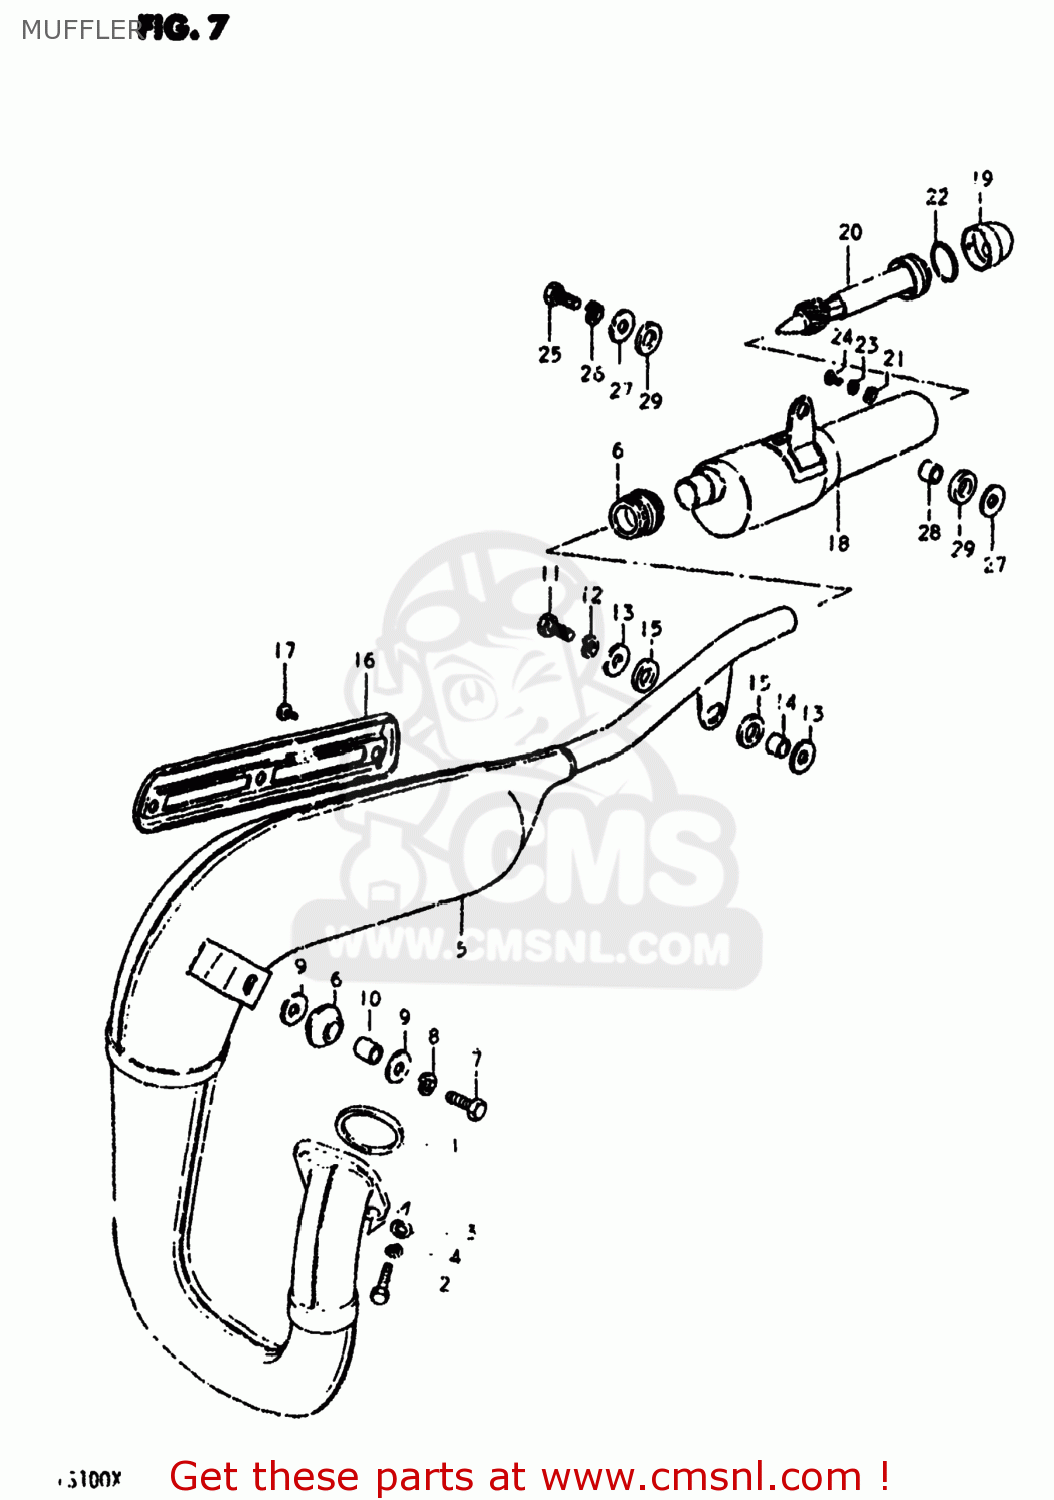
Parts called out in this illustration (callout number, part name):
1	GASKET,EXHAUST PIPE (NAS)
2	SCREW (6X25)
3	WASHER
4	LOCK WASHER
5	BODY,MUFFLER
6	DAMPER,MUFFLER,FR
7	BOLT
8	LOCK WASHER
9	WASHER (8.7X22X2)
10	SPACER (8X12X15)
11	BOLT
12	LOCK WASHER
13	WASHER
14	SPACER (8.6X13.8X9.8)
15	CUSHION
16	COVER,MUFFLER
17	SCREW
18	MUFFLER ASSEMBLY
19	COVER,SECOND MUFFLER TAIL
20	TUBE,MUFFLER CLEAN OUT
21	SCREW(6X8)
23	LOCK WASHER
24	WASHER
25	BOLT
26	LOCK WASHER
28	SPACER (8.6X13.8X9)
29	CUSHION
30	CONNECTOR,MUFFLER
